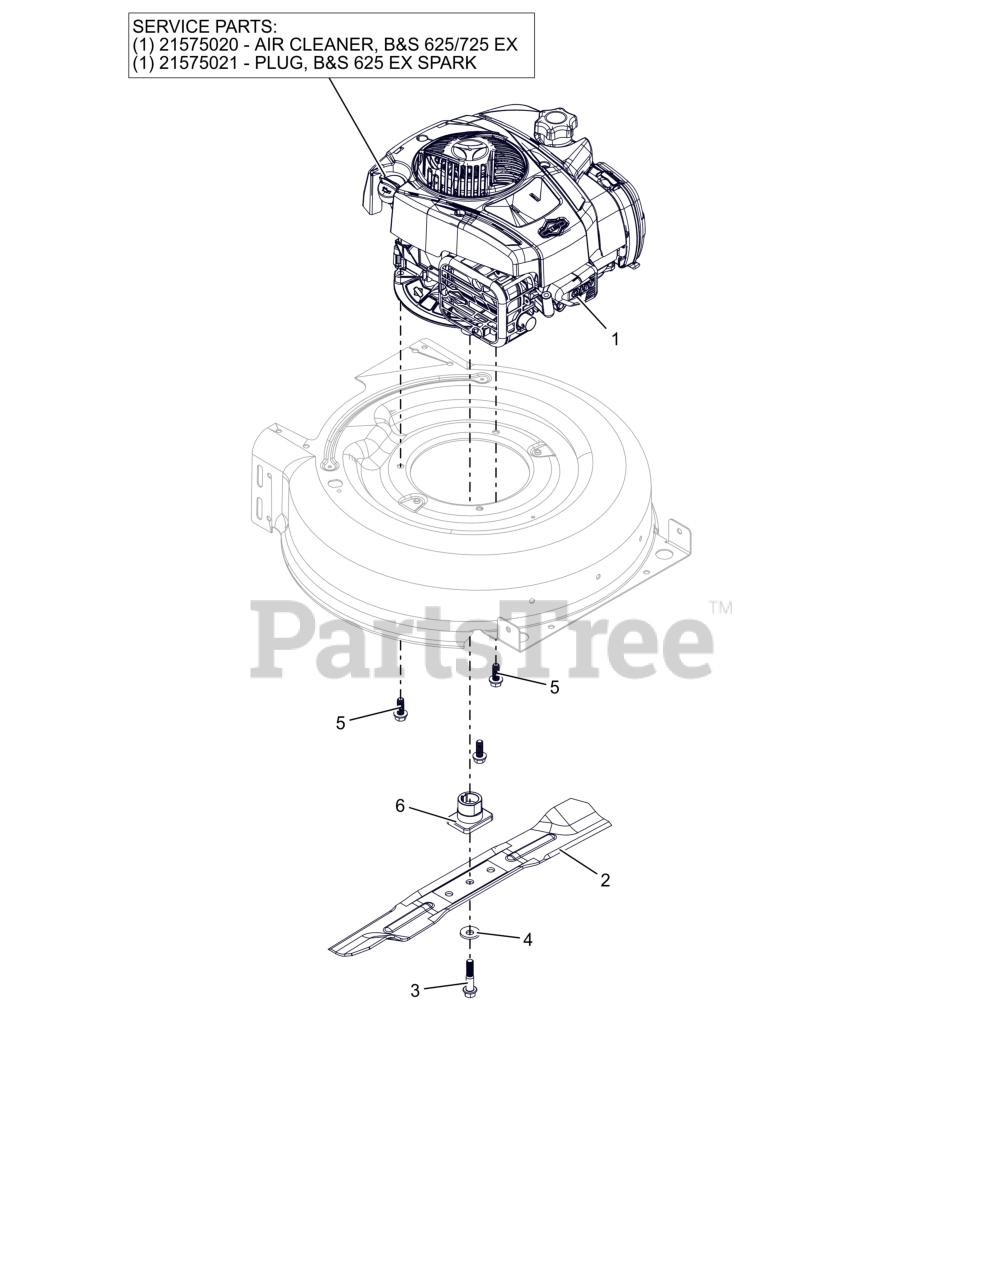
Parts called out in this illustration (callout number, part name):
1	ENGINE, BRIGGS 625 EX
1	AIR CLEANER- B&S 625/725 EX
1	PLUG- B&S 625 EX SPARK
2	BLADE, MOWER 21" HIGH LIFT
3	BLT-SHLDR .435X1.00X.38-24
4	WSHR, BLVL- .440X1.130X.120
5	SCR-TAP, 3/8-16X1.00 HWH
6	SPCR, BLADE - PUSH
